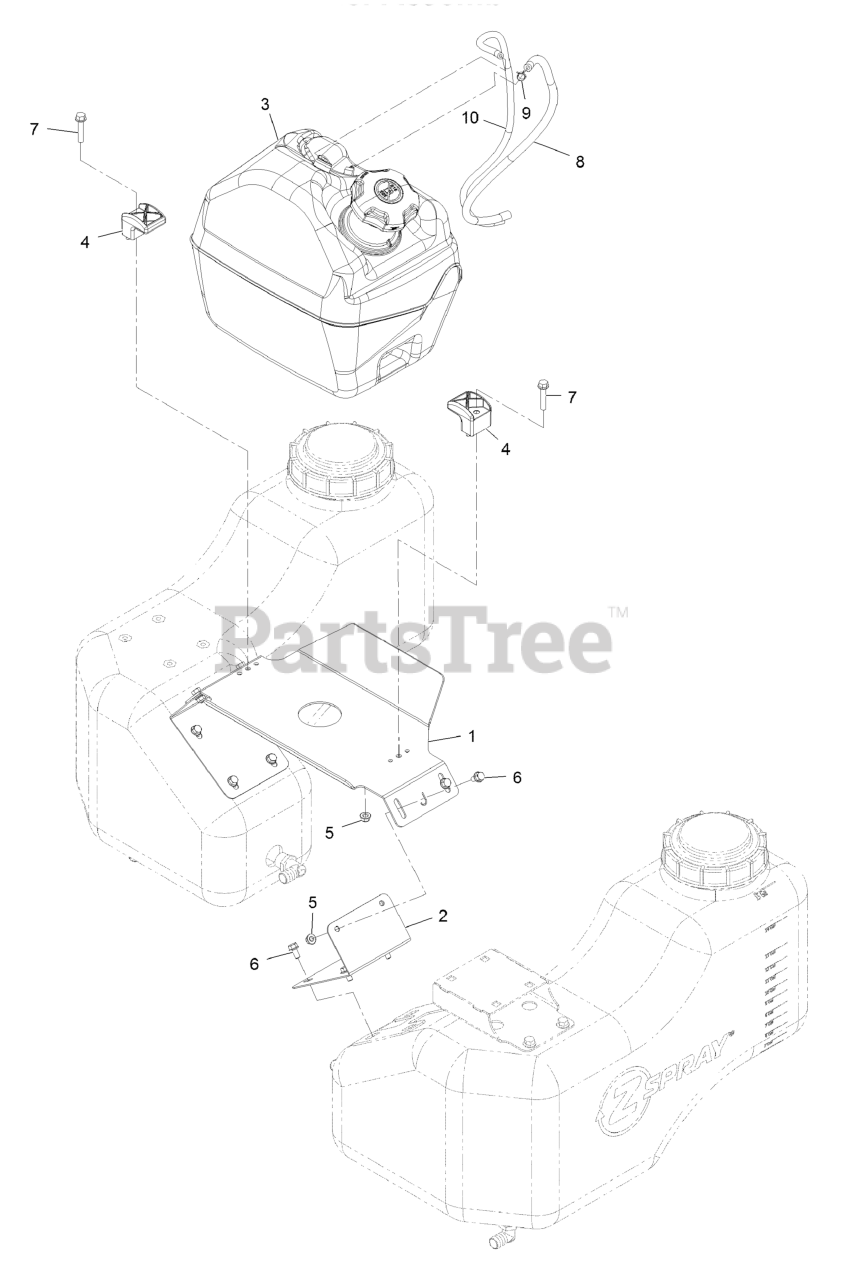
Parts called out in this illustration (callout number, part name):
1	Support-Fuel Tank
2	BRACKET-SUPPORT, GAS TANK
3	Fuel Tank ASM, 5 Gal
5	Nut-Hex Flange
6	Screw-HHF
7	Screw-HHF
8	HOSE-FUEL
9	CLAMP-HOSE
10	HOSE-FUEL
